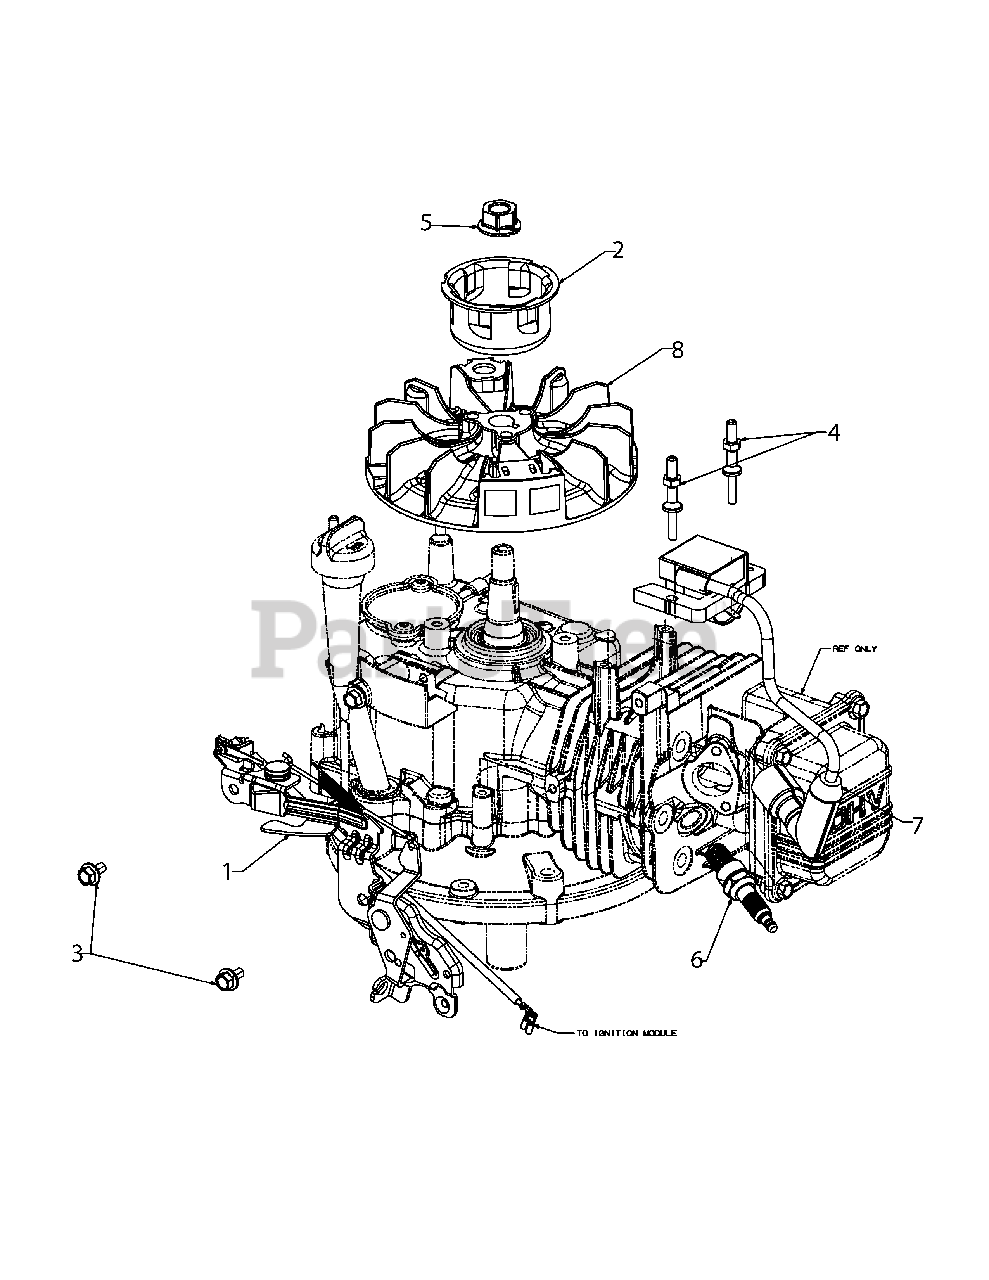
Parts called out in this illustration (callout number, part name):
1	Brake Asm:Flywhl
2	Cup-Start 195
3	Hhflg-M6-1:12 Cl8.
4	Stud-M5-8:22
5	Nut-Hex Flange M14
6	Plug:Spark
7	Ignition Module
8	Flywheel-195
